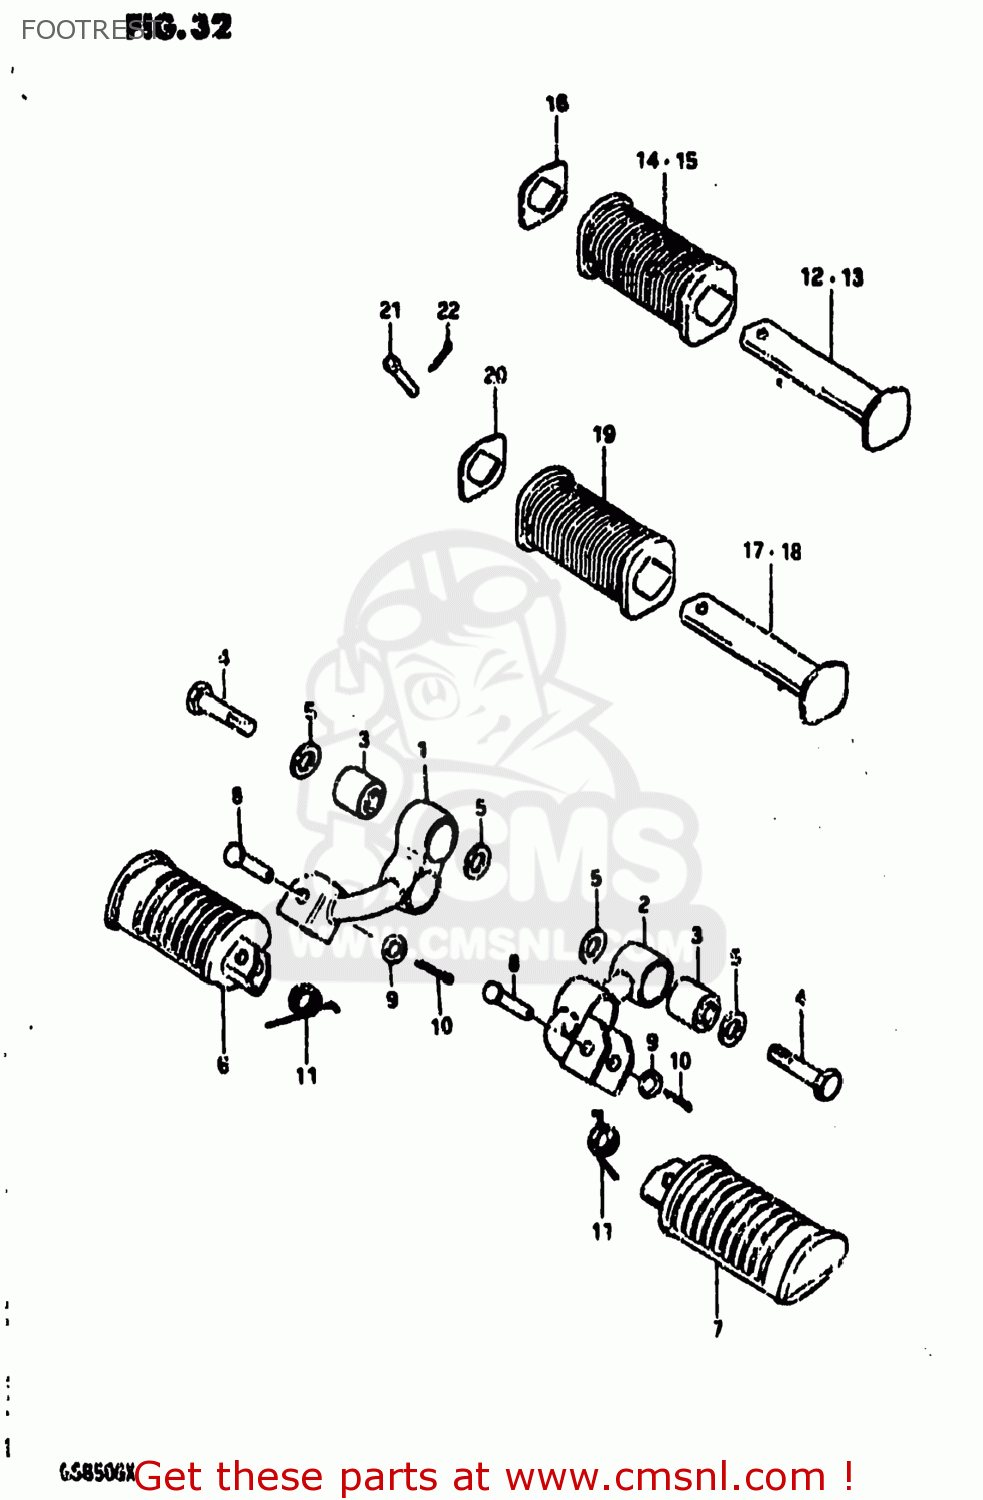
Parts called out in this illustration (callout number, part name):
1	BAR,FRONT FOOTREST,RIGHT
2	BAR,FRONT FOOTREST,LEFT
3	BUSH
4	BOLT
5	WASHER (10.1X21X2.3)
6	RUBBER,FRONT FOOTREST
7	FOOTREST
8	PIN
9	WASHER
10	PIN
11	SPRING
12	BAR,REAR FOOTREST
13	BAR,REAR FOOTREST
14	RUBBER,PILLION FOOTREST
15	RUBBER, LH
16	WASHER,REAR FOOTREST RUBBER
17	BAR,REAR FOOTREST,RIGHT
18	BAR,REAR FOOTREST,LEFT
19	RUBBER,PILLION FOOTREST
20	WASHER,PILLION FOOTREST RUBBER
21	PIN
22	PIN
